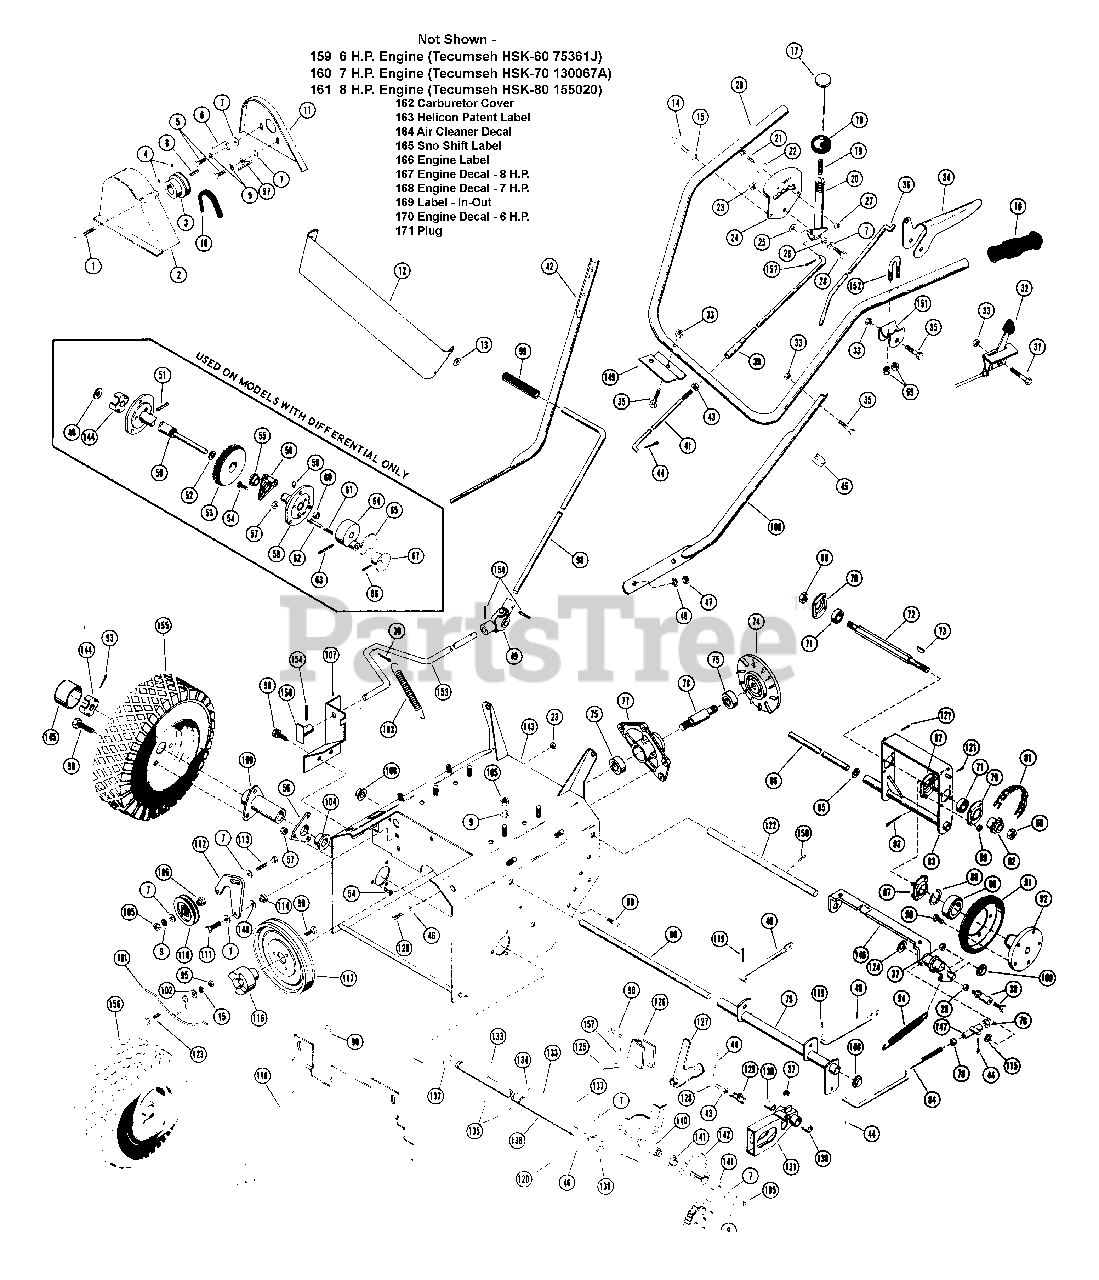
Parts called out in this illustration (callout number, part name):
68	NUT-LK-CTR .50-20 PL
69	NUT-LK TOP 10-24 PL
70	BEARING FLANGE
71	BRG-BALL .500X1.38X.437
72	HEX SHAFT
73	KEY-WDRF .125X.625X.250 SAE5
74	DRIVE PLATE
75	BRG-BALL .750X1.750X.50
76	SPINDLE
77	BEARING HOUSING
78	NUT-LK-TWIN .312-18 PL
79	FRONT CLUTCH LEVER
81	ROLLER CHAIN
82	9 TOOTH SPROCKET
83	DISC BRACKET
84	ADJUSTMENT LINK
85	WSHR-FL-STL .505X.875X.024 PL
86	BRACKET PIN
87	BEARING FLANGE
88	RG-RTNG-EXT 1.250X.050
89	BRG-N-THRST 1.26X2.18X.63
90	BLT-SERHFWH .31-18X.50 PL
91	FRICTION DISC
92	FRICTION DISC HUB
93	PIN-COTR .12 X 1.25 PL
94	SG-TENS .072X.50X5.31 WLD 25
95	NUT-HEX .250-20 PL
96	BLT-WHL .50-20X.75 GR5 PL
97	L H BELT FINGER
98	ATTACHMENT CLUTCH HANDLE
100	WHEEL HUB
101	BELT FINGER
102	WSHR-FL-STL.312X.734X.065PL
103	SG-TENS .125X.437X5.5 WLD 20
104	BSHG-FLG .750X1.000X.625X1.250
105	NUT-HEX .312-18
106	BEARING SPACER
107	CLUTCH BRACKET
108	CAP, .50 ROD YWZC
109	L H LOWER HANDLE BAR
110	IDLER
111	BLT-HEX .31-18X1.25 PL GR2
112	IDLER ARM
113	BLT-HEX .31-18X1.75 PL GR2
114	SHOULDER SPACER
115	WSHR-FL-STL .323X.625X.062 PL
116	JAW COUPLING
118	BOTTOM COVER
119	PIN-COTR .09X.75 PL
120	BLT-HEX .38-16X.75 PL GR2
121	PIN-HAIR INT .06X.18X.77
122	FORK SHAFT
123	BLT-HEX .25-20X.75 PL GR2
124	WSHR-FL-STL .505X.880X.072 PL
125	CLEVIS PIN
126	LEVER BRACKET
127	TRANSFER LEVER
128	CONNECTING LINK
129	BALL JOINT
130	BSHG-SLV .500X.625X.500 BR
131	SLIDING FORK
132	WSHR-FL-STL .755X1.375X.125
133	KEY-FTHR .188X1.25X.187 SAE
134	KEY-WDRF .25X.750X.313 SAE91
135	PIN-ROLL .188X1.00
136	AXLE SHAFT
137	BLT-HEX .31-18X2.75 PL GR2
138	BRACKET
139	SPUR GEAR, FELLOWS 35T .750 ID
140	PINION STUB SHAFT
141	BSHG-FLG .625X.750X.500X.875BR
142	PINION & SPROCKET
143	TRACTOR FRAME
144	SPINDLE CUP
145	HUB CAP
146	REAR CLUTCH LEVER
147	PIVOT SPACER
148	WSHR-FL-STL .505X.875X.024 PL
149	ROD HANGER BRACKET
150	CLUTCH INTERLOCK LEVER
151	HANDLE PIVOT
153	ENGAGEMENT ROD
154	PIN-ROLL .125X.75
155	TIRE & WHEEL ASSEMBLY GOODYEAR
155	TIRE 4.10/3.50X6
155	TUBE
155	WHL 6 IN O.D.
156	TIRE & WHEEL ASSEMBLY CARLISLE
156	TIRE 12.5/4.50-6
156	TUBE
156	WHL 6 IN O.D.
157	PIN-COTR .12X1.0 PL
158	PIN-HAIR INT .08X.38X1.42 YWZC
159	6 H.P. Engine(Tecumseh HSK-60 75361J) orReplacement
160	7 H.P. Engine(Tecumseh HSK-70 130067A) orReplacement
161	8 HP Eng.(Tecumseh HSK-80 155020) or Replac.
162	CARBURETOR COVER
164	AIR CLEANER DECAL
167	8 H P ENGINE DECAL
168	7 HP ENGINE DECAL
170	6HP ENGINE DECAL
